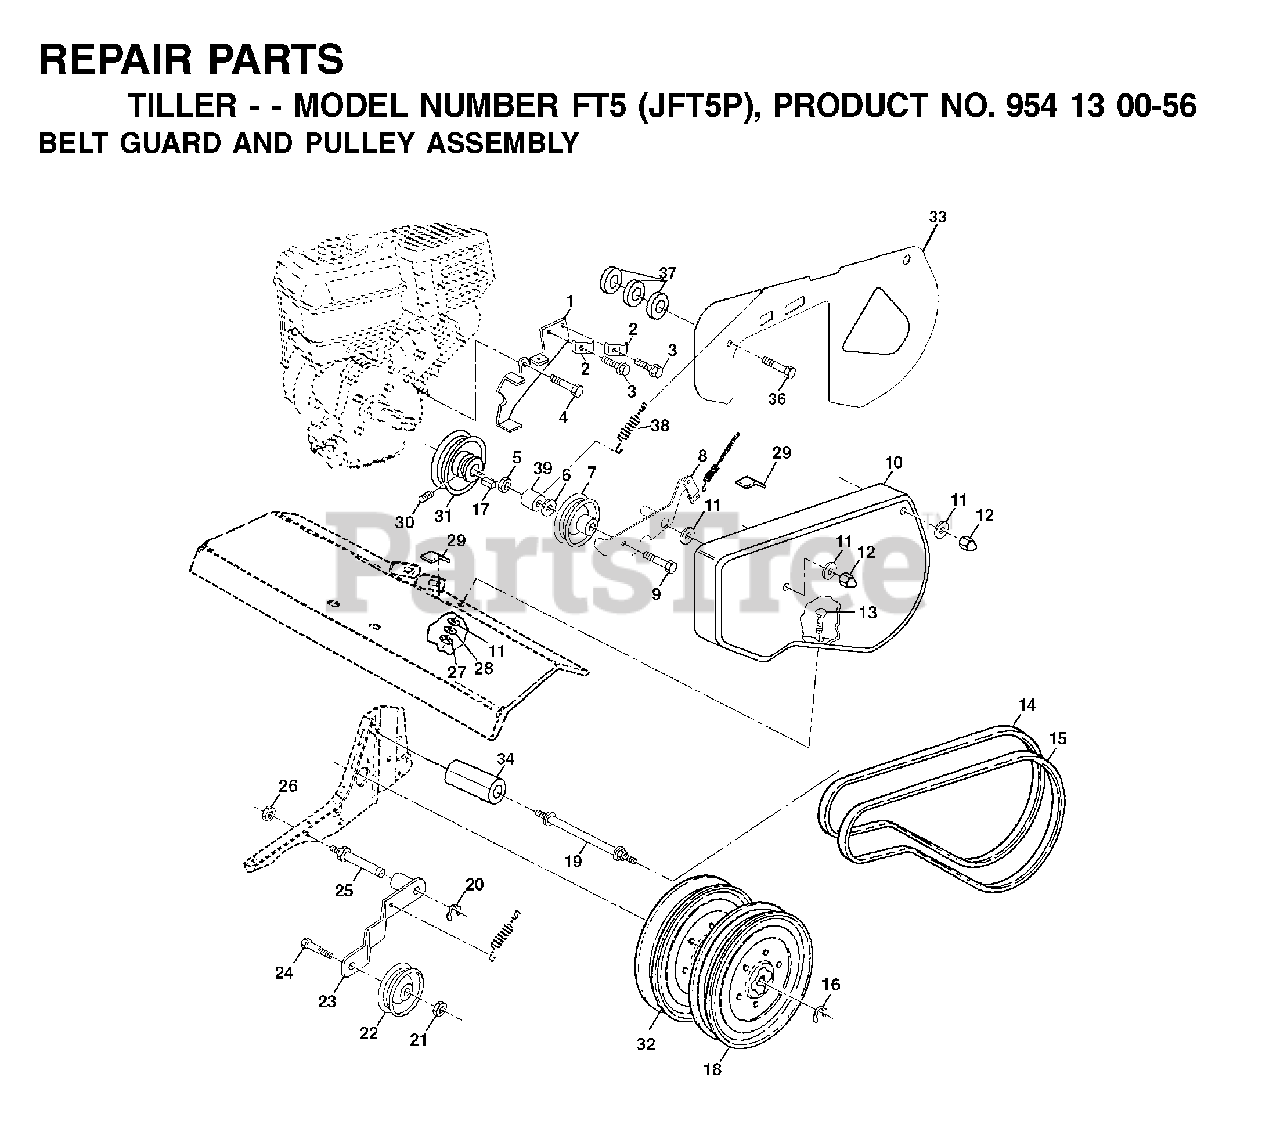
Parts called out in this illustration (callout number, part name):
1	RP BRKT.ASM.GUARD.BELT
2	CONDUIT CLIP T
3	TAPPING SCREW
7	PULLEY
8	ARM
9	BOLT
11	WASHER
12	CAP
15	BELT
16	RETAINING RING LT
18	SHEAVE,TRANS."D"
20	RING, KLIP
21	NUT
22	PULLEY, IDLER
23	ARM, IDLER
25	SHAFT.IDLER.TILLER
26	JAM NUT TI
27	NUT
28	LOCKWASHER
29	PAD IDLER TI
32	SHEAVE.TRANS
37	WASHER
38	SPRING.EXTENSION
